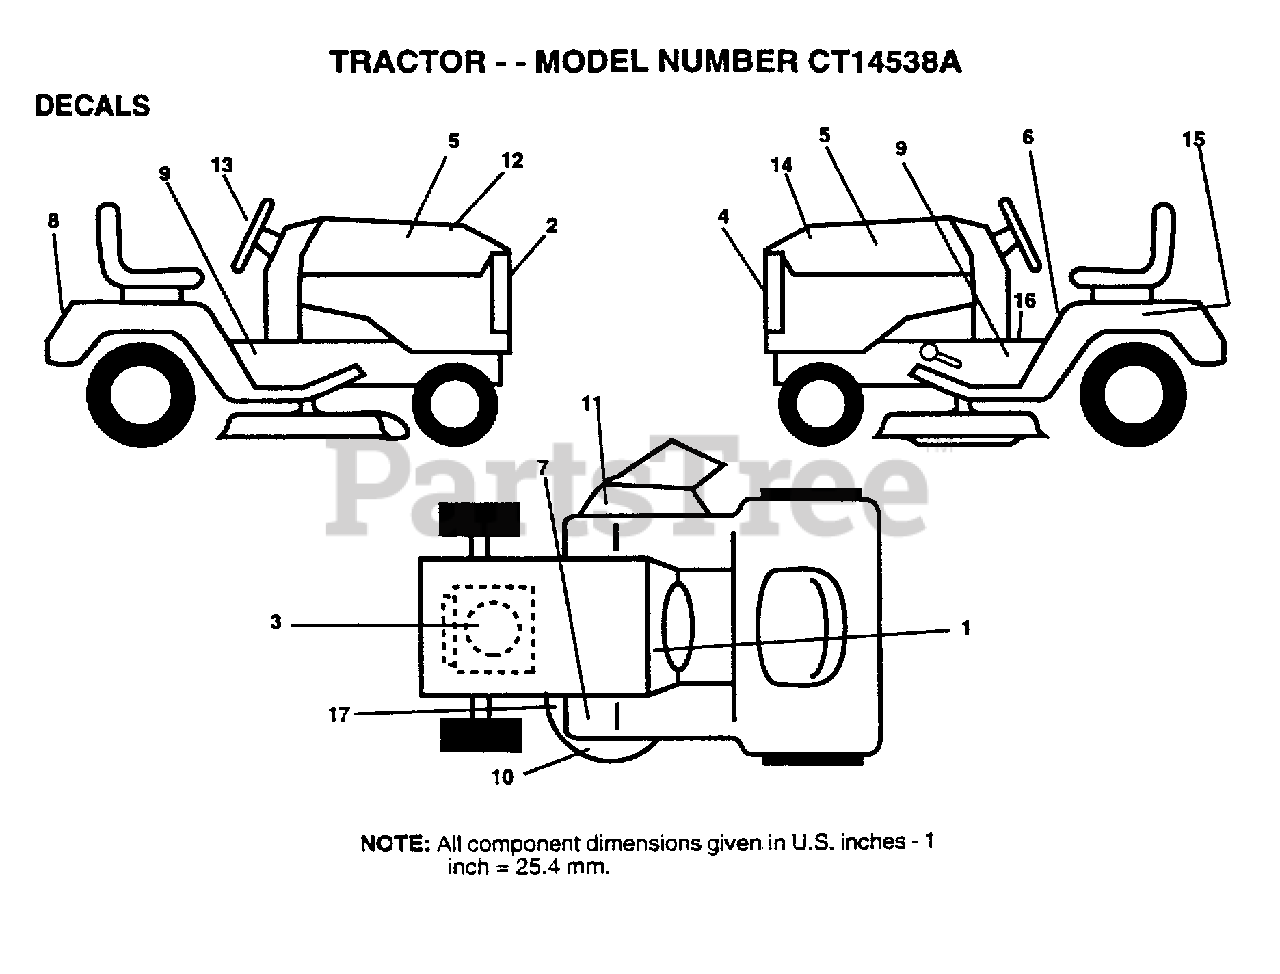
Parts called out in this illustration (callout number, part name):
1	DECAL.DASH.INSTR.
2	GRILL DECAL
3	DECAL, ENGINE
5	DECAL.INS.HD.RALL
6	DECAL CAUTION
7	DECAL T
8	FENDER DECAL
11	"DECAL, WARNING"
12	DECAL HOOD RH RLY
13	"DECAL,STR WHL"
14	DECAL HOOD LH RLY
15	DECAL
16	DECAL BRAK PARK
17	DECAL
